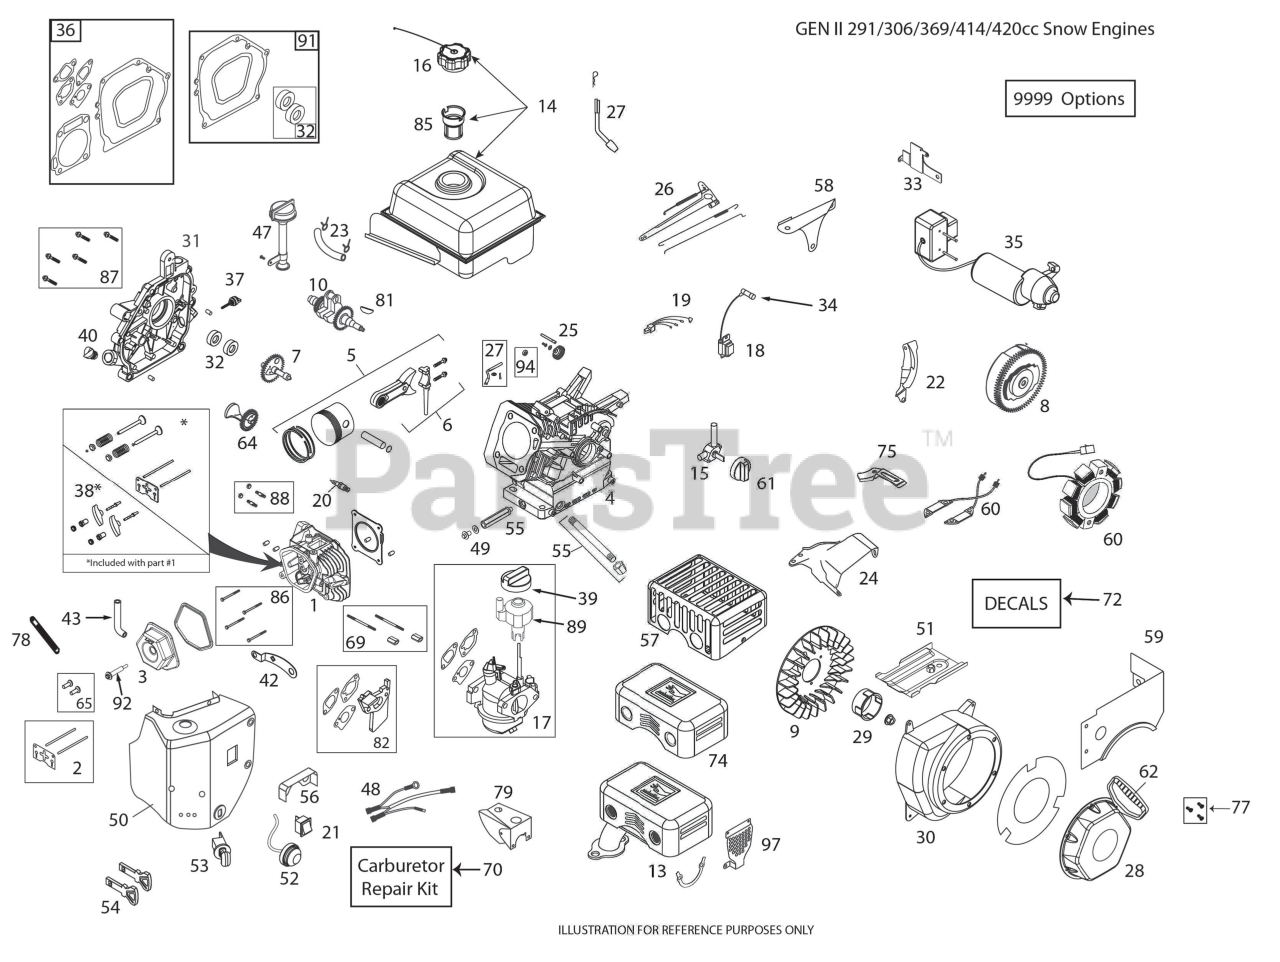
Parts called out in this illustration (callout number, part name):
1	CYLINDER.HEAD.ASSY(SK2911000)
2	PUSH ROD TAPPET KIT
3	VALVE.COVER.LCT.414CC.
5	PISTON.AND.ROD.ASSY(SK2911400)
7	CAMSHAFT.LCT.291CC
8	FLYWHEEL.EL.ST.SKSNO2401.1
9	FLYWHEEL.FAN
10	CRANKSHAFT
13	MUFFLER ASSY LCT SNO
14	FUEL TANK ASSY - SNOW (291CC)
15	FUEL.PETCOCK.SNOW(SKSN4900)
16	FUEL.TANK.CAP.SNOW(SKSN4301)
17	CARBURETORS
18	COIL.IGN.CDI.SKSN2403.1
20	SPARK.PLUG(2083810)
21	ON/OFF.SWITCH.SNOW(SKSN4403)
23	FUEL HOSE KIT
24	TOP.SHIELD.LCT.
25	GOVERNOR.GEAR.ASSY(SK2912900)
26	GOVERNOR.ARM.ASSY.(SKSN2502)
27	GOVERNOR.SHAFT.(SK2913100)
28	STARTER RECOIL.291/306CC.LCT
29	STARTER CUP.LCT.291/306CC
30	BLOWER HOUSING.LCT.291/306CC W
31	CRANKCASE.COVER.ASY(SK2913600)
32	OIL.SEAL.KIT(SK2913900)
33	SWITCHBOX BRACKET ES LCT 291 S
34	SPARK.PLUG.BOOT.SNW,SKSN4691.1
35	STARTER, ELECTRIC, 230V
36	ENGINE.GASKET.KIT(SK2914300)
37	DIPSTK.OIL.BLK.LCTSK4143711.1
38	ROCKER ARM KIT
39	CHOKE.KNOW.SNOW(SKSN4500)
40	NONREMVABLE.OIL.PLUG(SK4143715
42	CDI.BOX.BRKT.SNOW(SKSN4402)
43	BREATHER TUBE LCT 291/369/414
47	HIGHOIL.FILL.ASSY.KIT(SKSN4911
48	WIRE.HARNESS(SKSN4406)
50	HEATER.BOX.ASSY.SNOW(SKSN2100)
51	SHIELD.CYLINDER.SNOW(SK4141010
52	PRIMER.BULB.ASSY(SKSN4304)
53	KEY.SWITCH.ASSY.SNOW(SKSN4401)
54	KEY SET(2 KEYS) SKSN0407.1
55	OIL PIPE DRAIN EXTENDED.LCT SK
56	SHIELD.VAPOR(SKSN4606)
58	GOVERNOR.LINK.SHIELD(SKSN2501)
59	FUEL TANK SKIRT.LCT.291/306CC
60	ALTERN.60WATT.SKSN2402.1
61	FUEL KNOB-SNOW
62	HANDLE.RECOIL.DELUXE.LCT
65	TAPPET KIT.LCT.SK2911005.1
69	STUD.CARB.MOUTING.KIT.291CC
70	CARBURETTOR REPAIR KIT 291CC/4
72	ARIENS 414 SNOW DECAL KIT
74	ARIENS 414 SNOW DECAL KIT
75	WIRE GUARD
77	BOLT.KIT.RECOIL.LCT.ALL.ENGINE
79	SHIELD CARBURRETOR COVER 414
82	SPACER.CARBURETOR.291CC.LCT
85	STRAINER.FUEL.TANK.LCT.208CC
86	KIT.BOLT.CYLINDER.HEAD.(4PC)
87	KIT.7-BOLT.CRANKCASE.CVR.291CC
88	STUD.MUFFLER.KIT.LCT
89	KNOB LCT.SKSN5325.1 SPEED
91	GASKET KIT CRANKSHAFT.LCT
92	CENTER VALVE COVER BOLT
97	GUARD.EXHAUST
9999	KIT.BOLT.LCT.SK9990.1
9999	HIGH.ALTITUDE.JET.6000FT ANDUP
